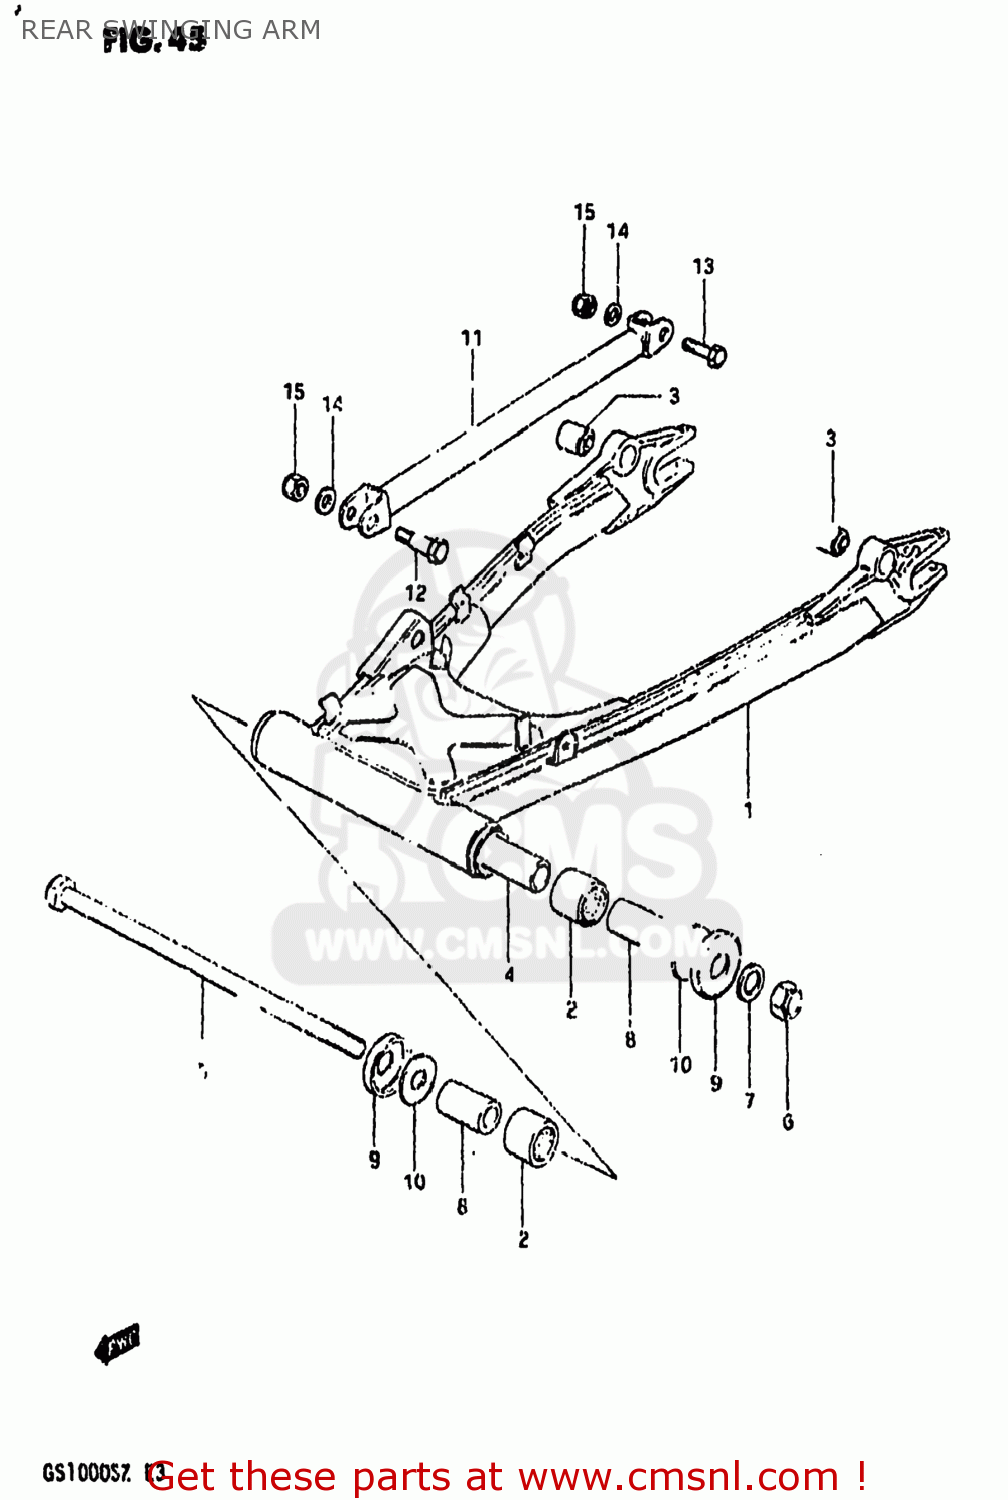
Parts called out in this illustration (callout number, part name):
1	SWING ARM ASSEMBLY,REAR
2	BEARING(25X33X30)
3	BUSH
4	SPACER,RR SWGARM PIVOT CTR
5	SHAFT,REAR SWING ARM
6	NUT 16MM
7	WASHER
8	SPACER,RR SWGARM PIVOT
9	COVER,RR SWINGINGARM PIVOT
10	WASHER
11	TORQUE LINK, REAR
12	BOLT
13	BOLT(10X39)
14	WASHER
15	NUT
